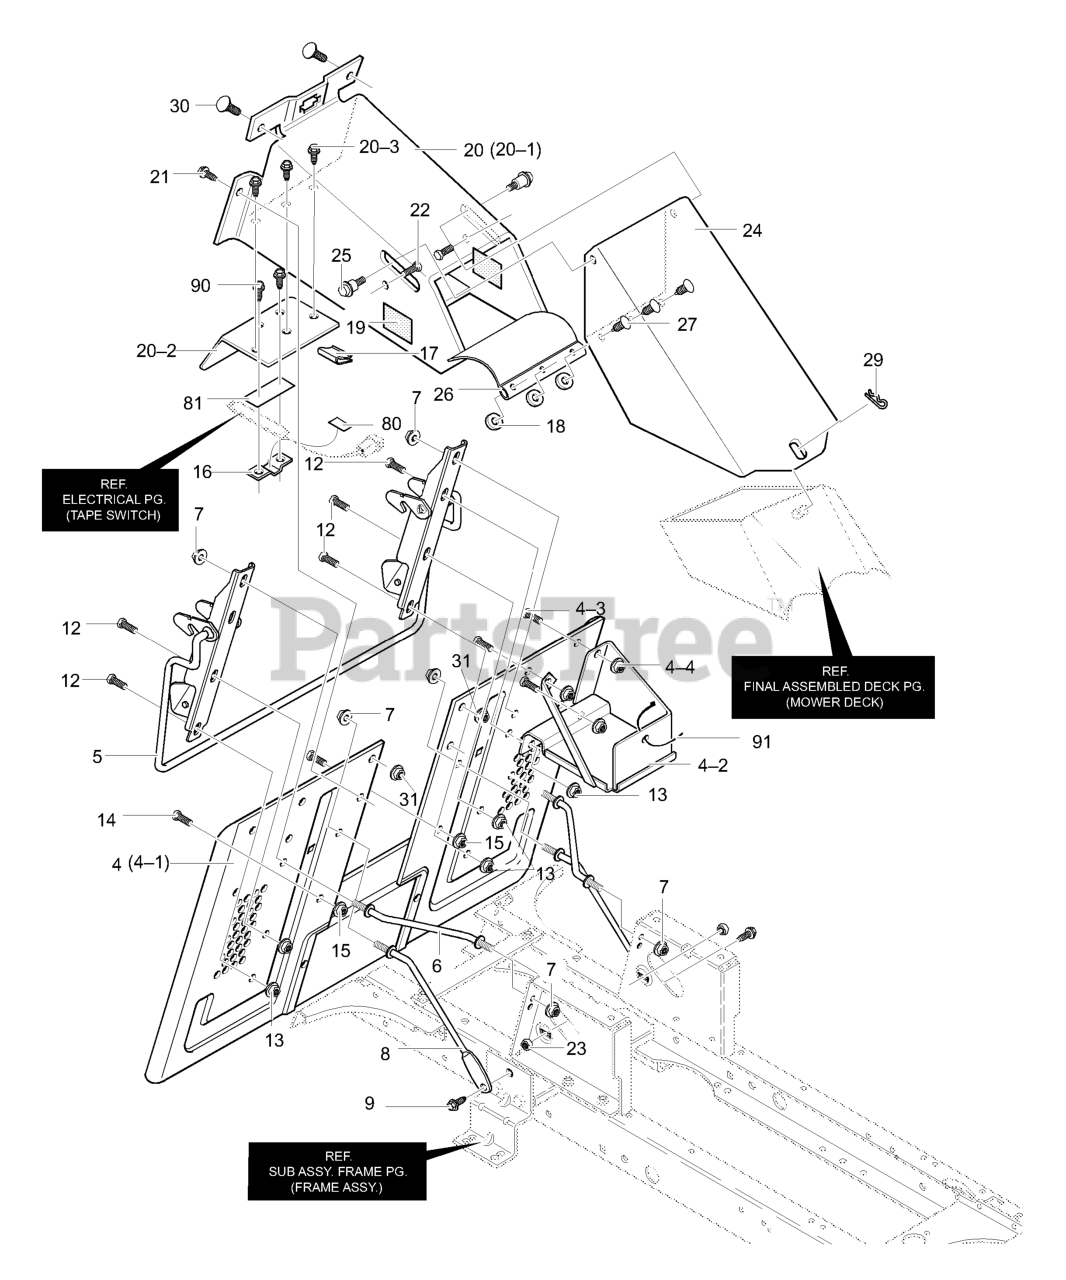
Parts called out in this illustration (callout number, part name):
4	ASSEMBLY, Back Plate/Battery
4-1	ASSEMBLY Back Plate Flat
4-2	Battery Tray Assembly
4-3	SCREW, 5/16-18 x 0.50
4-4	NUT, 5/16-18 Hexwdfllk
5	Weldment - Latch Lever
6	ROD, Brace
7	NUT, 3/8-16 Hwdfl Whiz-lock
8	ROD, Brace
9	SCREW, 5/16-18 x 0.75
12	SCREW, 5/16-18 x 0.75
13	NUT, 5/16-18 Hexwdfllk
14	SCREW, 5/16-18 x 0.75
15	NUT, 5/16-18 Hexwdfllk
16	BRACKET, Flex Switch Mting
17	Wire Clip, Adhesive
18	FLATWASHER
19	Pad, Adhesive
20	Asm., T/A Shield & Chute
20-1	CHUTE Weld Asm. Upper
20-2	SHIELD, Transaxle
20-3	SCREW, 1/4-20x.63
21	SCREW, 5/16-18 x 0.75
22	BOLT, Carriage 5/16-18x.75
23	NUT, 5/16-18
24	MIDDLE CHUTE ASSEMBLY
25	BOLT, Shoulder
26	Flap, Chute
27	FASTENER, Ratchet
29	PIN, Hair
30	BOLT, Carriage 5/16-18x.75
31	NUT, 5/16-18
80	Tape, Dble Sided Foam 3/4"
81	Tape, Dble Sided Foam 3/4"
90	SCREW, 1/4-20x.63
91	Cable Tie
